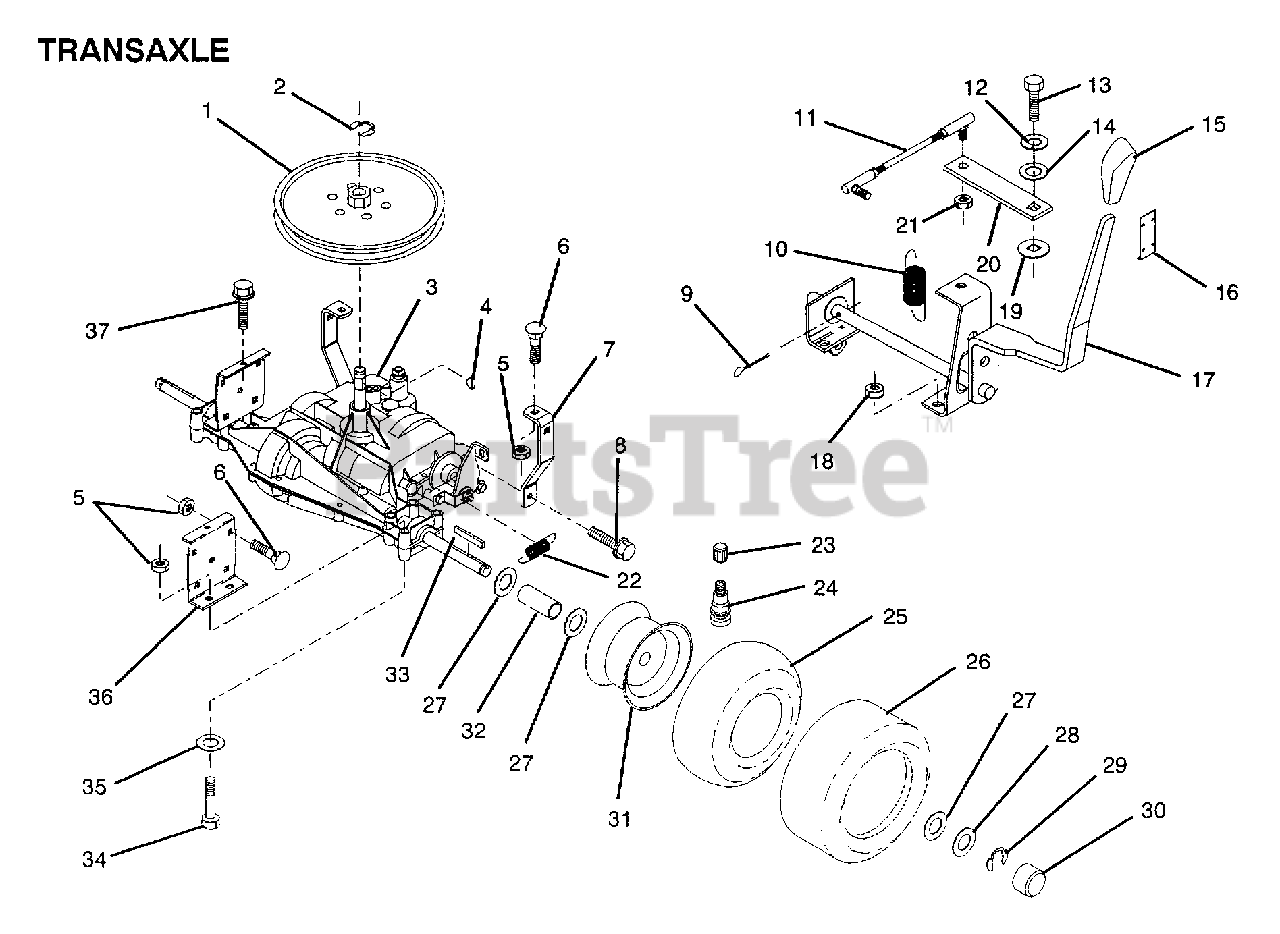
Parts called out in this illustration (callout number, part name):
1	PULLEY
3	TRANSAXLE PEERLESS 5 SPEED
6	BOLT
7	"STRAP,TORQUE"
8	SCREW LT
9	PIN COTTER 1/8
10	EXT SPRING
11	LINK SHIFT
12	LOCKWASHER
14	WASHER LT
15	"KNOB,SHT CONTROL"
16	KNOB RETAINER
17	SHIFT HANDLE ASSY
19	WASH-SHFT PLT LT
21	NUT.LOCK.5/16-24
23	VALVE CAP
24	VALVE STEM LT
25	TUBE.16X6.5/7.5-8
27	WASHER
28	WASHER
29	E-RING LT
30	HUB CAP
32	SPACER
33	SQUARE KEY
34	BOLT
35	WASHER
36	"BRKT,TRANSAXLE"
37	SCREW
